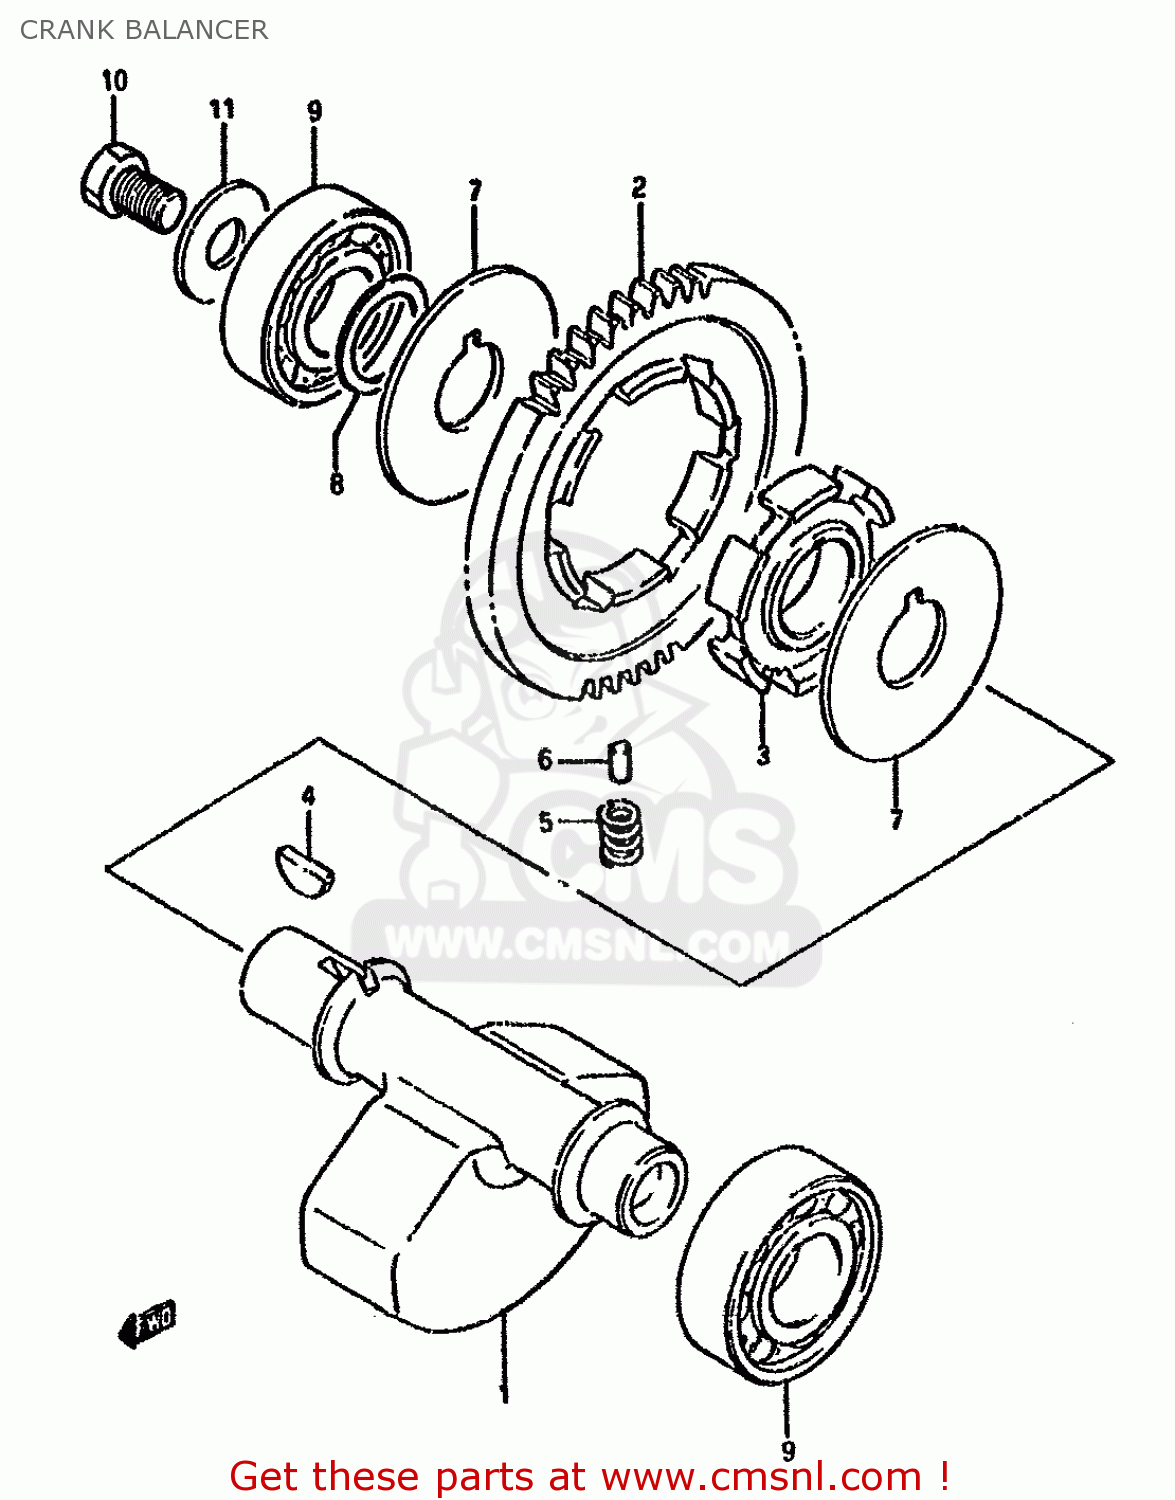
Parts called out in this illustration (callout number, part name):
1	BALANCER,CRANKSHAFT
2	GEAR,CRANK BALANCER
3	RACE,CRANK BALANCER DRIVEN GEAR
4	KEY 4MM
5	SPRING
6	PIN
7	WASHER
8	THRUST WASHER
9	BEARING(20X47X14)
10	BOLT
11	WASHER(10X28X2.2)
